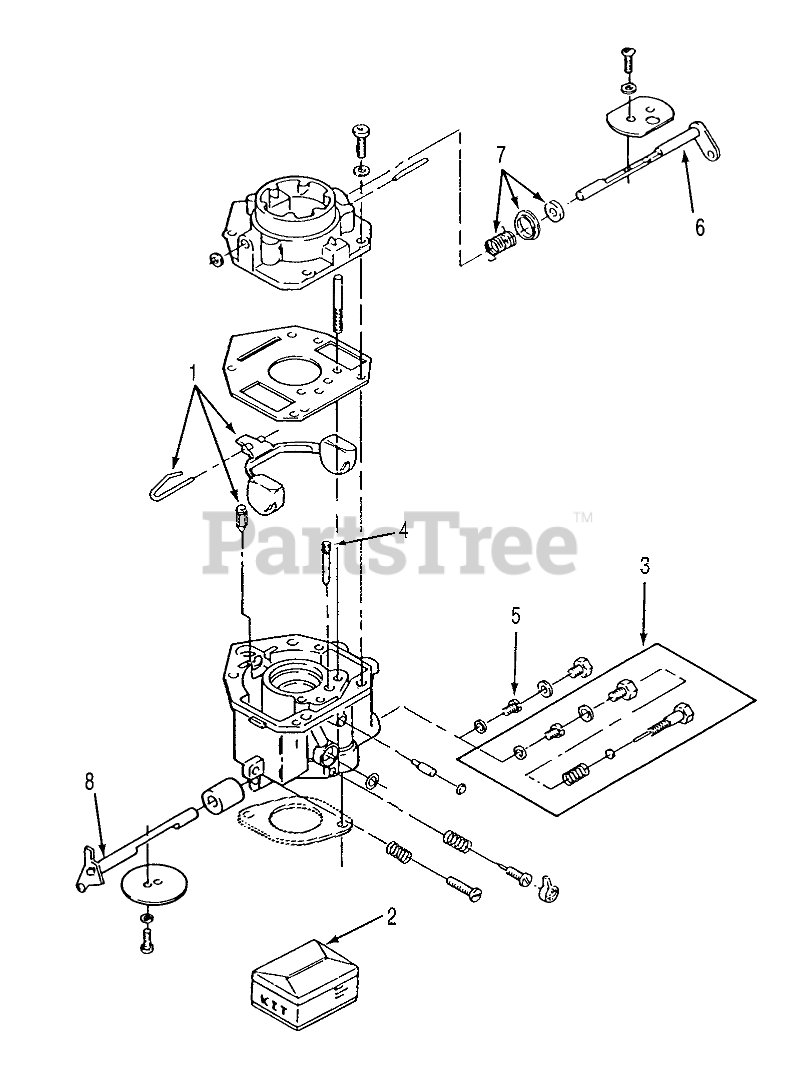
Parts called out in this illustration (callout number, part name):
1	Float Kit (Includes Float, Pin and Valve)
2	Repair Kit (Includes Screw and Plug Package, Gasket Package, Float Valve, Idle Adjustment Needle and Spring, Mounting Gaskets, Idle Limit Cap)
3	Variable Jet Kit-Optbnal (High Altitude Application Includes Power Jet and Gasket, Retainer, Power Needle Spring, Power Needle and Power Plug Gasket)
4	Idle Jet
5	POWER JET
6	Choke Shaft Kit (Includes Choke Valve, Valve Set Screw and Air Filter)
7	Choke Lever Kit (Includes Choke Lever Ring, Choke Spring and Choke Collar)
8	Throttle Shaft Kit (Includes Valve Set Screw, Air Filter and Throttle Valve)
